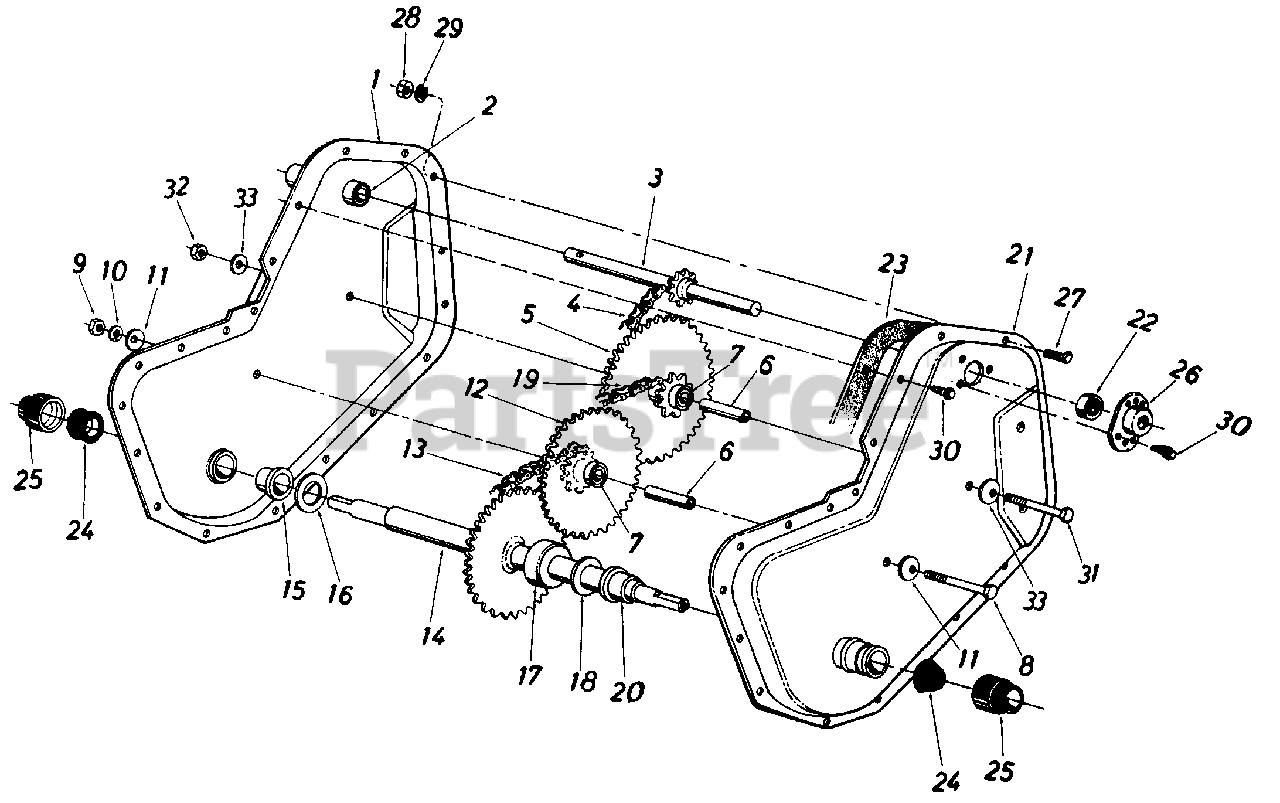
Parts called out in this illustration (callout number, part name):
1	Chain Case Half Ass'y.-R.H.
2	Bearing 518" I.D. x .813" O.D. x 1.31" Lg.
3	Input Shaft Ass'y.
4	Chain #35-3/8" Pitch x 44 Link
5	Sprocket and Hub Ass'y.
6	Bearing Inner Axle
7	Sleeve Brg. 5/8" l.D. x 3/4" O.D. x 1.50
8	Hex Bolt 3/8-24 x 2 50" Lg.
9	Hex Ins. L-Nut 3/8-24 Thd.
10	L-Wash. 3/8" I.D.
11	Bell-Wash. .41" I.D. x 1.13" O.D. x .03
12	Sprocket & Hub Ass'y. 9T-22T
13	#420 Chain 1/2 Pitch x 28 0 Links Endless
14	Wheel Shaft Ass'y.
15	Flange Bearing
16	Fl-Wash. .88" l.D. x 1.5" O.D. x .03
17	Spacer 7/8" I.D. x 13/4" O.D. x.68" La.
18	Fl-Wash. .88" l.D. x 1.50" O.D. x .03
19	#420 Chain 1/2" Pitch x 30 0 Links Endless
20	Flange Bearing
23	Gasket
26	Bearing Housing
27	Hex Bolt 1/4-28 x 5/8" Lg.
28	Hex Nut 1/4-28 Thd.
29	L-Wash. 1/4" l.D.
30	Hex Wash. S-Tap Scr. 1/4-20 x .50" Lg.
31	Hex Bolt 5/16-18 x 2.5" Lg.
32	Hex Cent. L-Nut 5/16-18 Thd.
33	Fl-Wash. 5/16" l.D.
